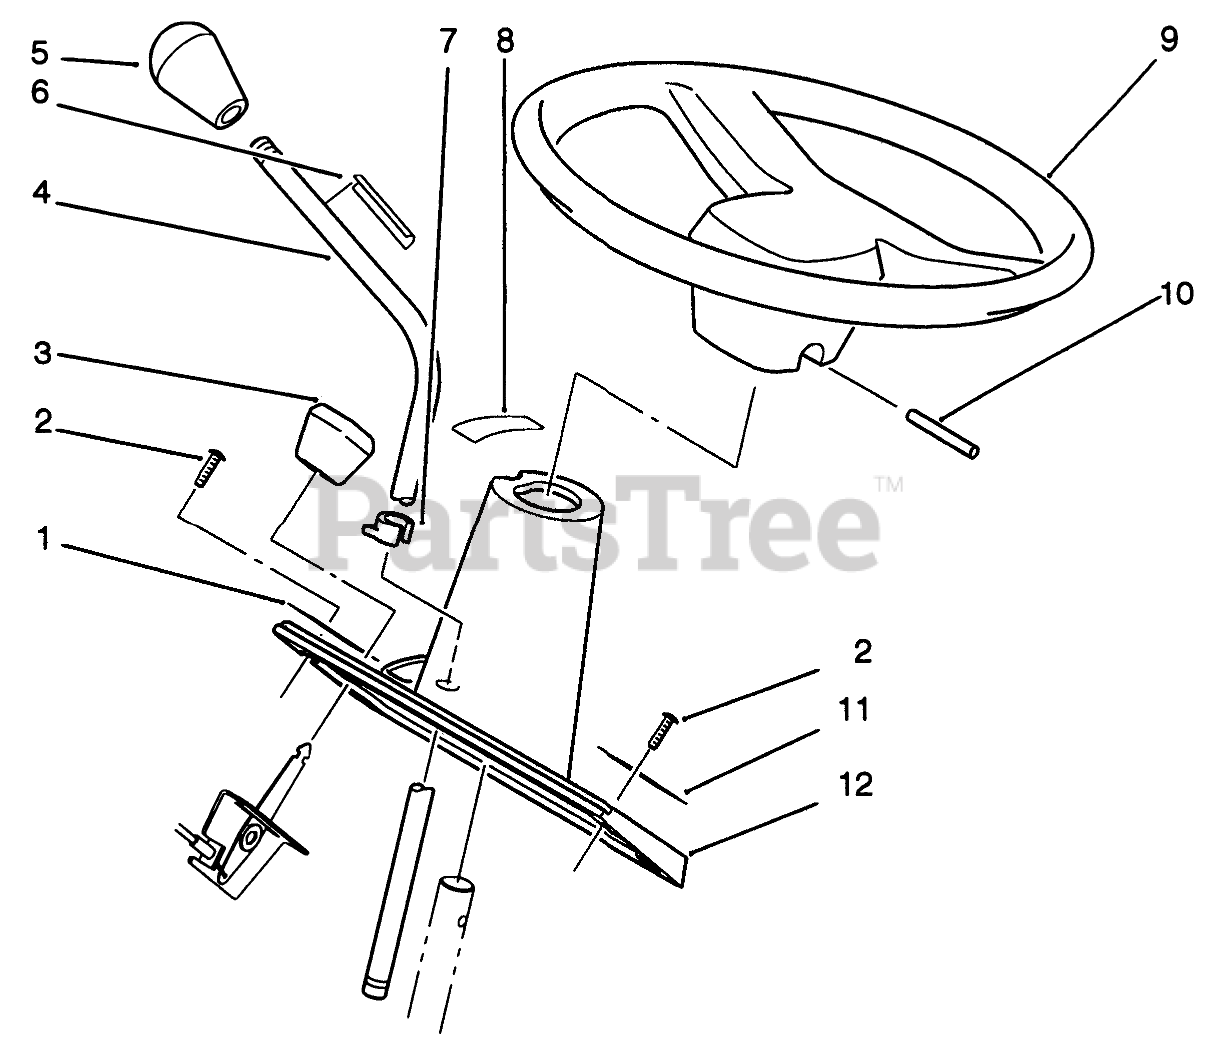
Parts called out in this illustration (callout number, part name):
1	DECAL-THROTTLE
2	SCREW
3	KNOB-THROTTLE
4	ROD-SHIFT LEVER
6	DECAL-MOTION CONTROL
7	POINTER
8	DECAL-HYDRO MOTION
9	STR'G-WHL 13" TORO
10	PIN-ROLL
11	DECAL-HEIGHT OF CUT
12	CONSOLE
